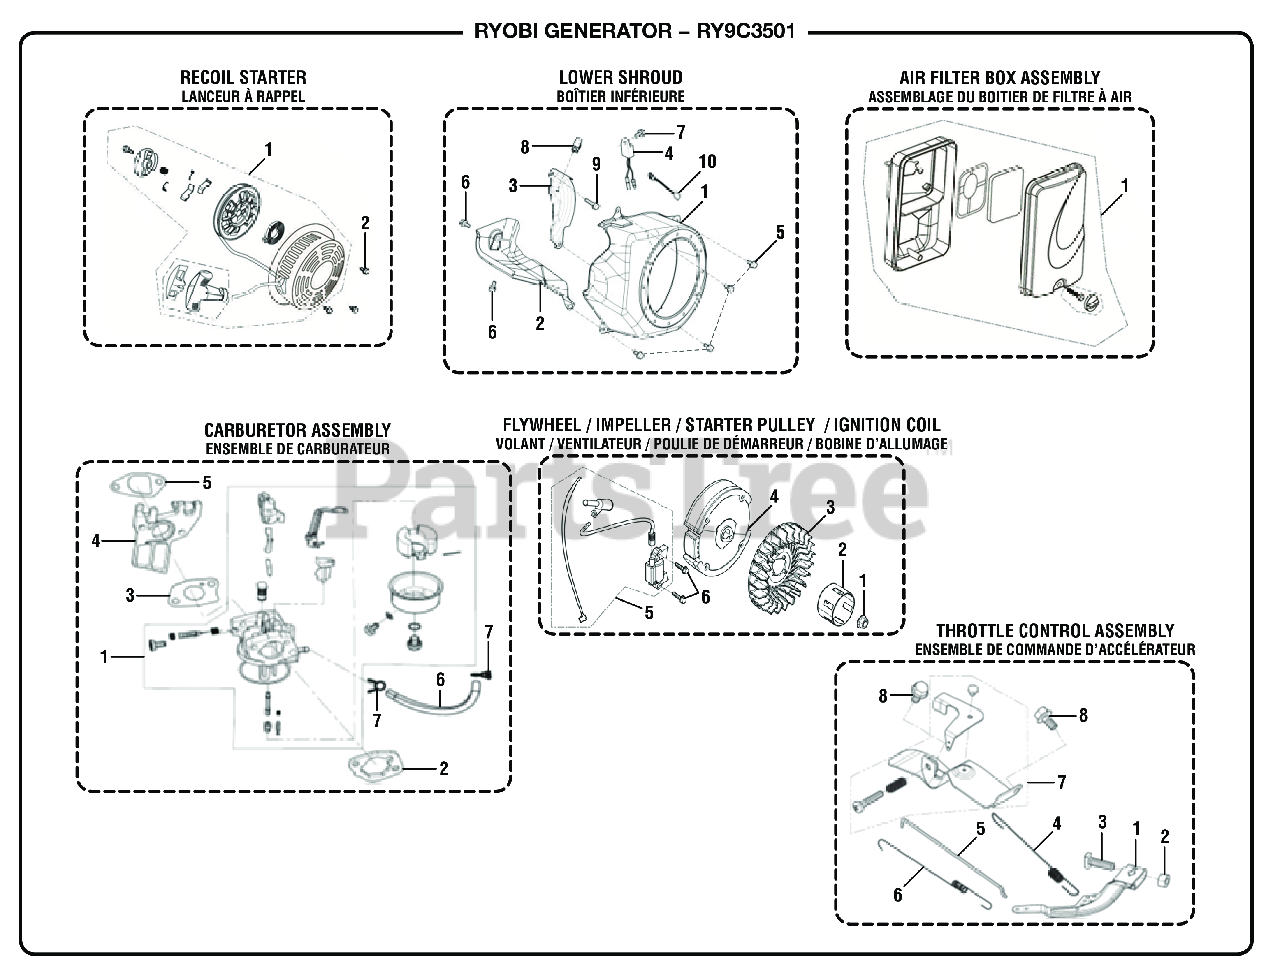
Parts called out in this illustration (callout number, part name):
1	Recoil Starter Assembly
1	Carburetor Assembly
1	Air Cleaner
1	Flywheel Nut
1	Governor Support Assembly
2	Cylinder Body Shroud
2	Air Cleaner Gasket
2	Starter Pulley
3	Lower Shield
3	Carburetor Gasket
3	Impeller
3	Governor Support Bolt
4	Oil Protector
4	Carburetor Insulator Plate
4	Flywheel Assembly
4	Governor Spring
5	Carburetor Insulator Gasket
5	Ignition Coil
5	Governor Rod
6	Throttle Valve Return Spring
7	Clamp
7	Throttle Control Assembly
8	Collar
10	Engine Stop Wire
